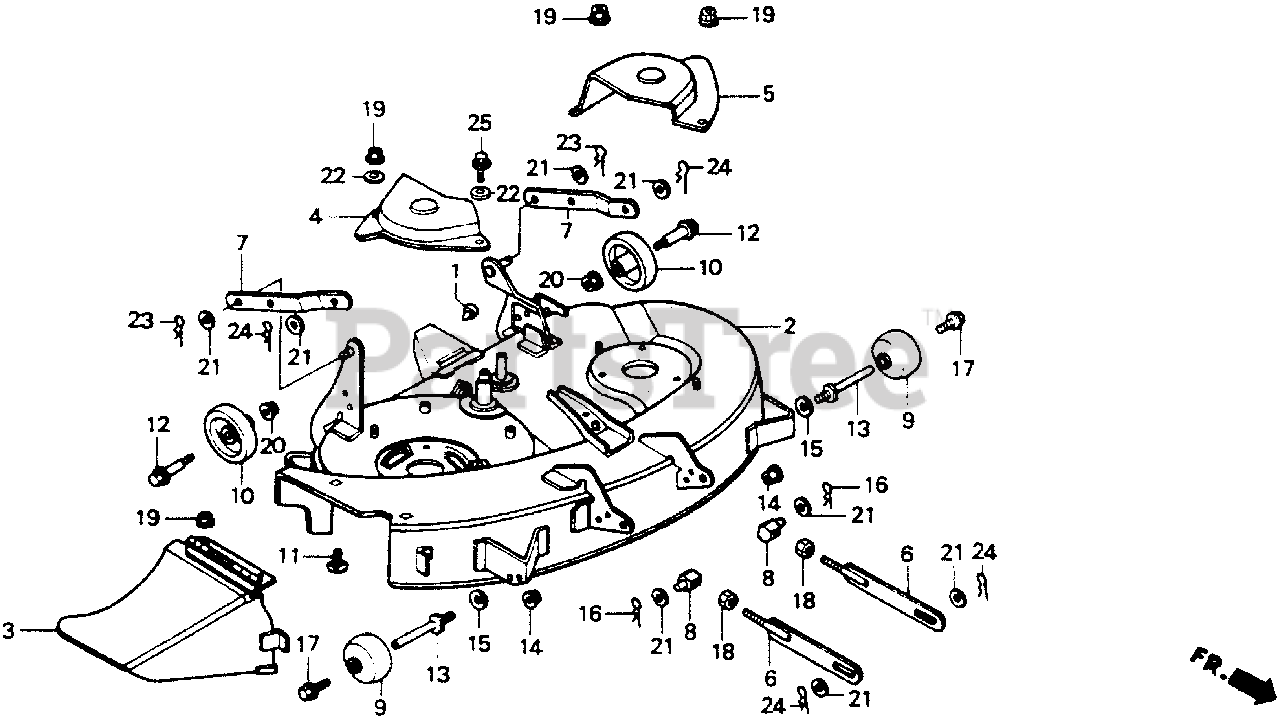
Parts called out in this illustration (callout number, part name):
1	RUBBER, STOPPER
2	HOUSING, CUTTER (NOT AVAILABLE)
3	ADAPTER, DISCHARGE *NH190M* (VINTAGE GRAY METALLIC)
4	COVER, R. BELT *NH190M* (VINTAGE GRAY METALLIC)
5	COVER, L. BELT *NH190M* (VINTAGE GRAY METALLIC) (NOT AVAILABLE)
6	LINK, FR. DECK
7	LINK, RR. DECK
8	PIN, FR. LINK ADJUSTING
9	ROLLER, ANTI-SCALP
10	ROLLER, RR. ANTI-SCALP
11	BOLT, SPECIAL (9X15)
12	BOLT, ANTI-SCALP ROLLER
13	SHAFT, ANTI-SCALP ROLLER
14	NUT, FLANGE (12MM)
15	WASHER, SPECIAL (12MM) (NOT AVAILABLE)
16	PIN, LOCK (2.3MM)
17	BOLT-WASHER (8X12)
17	BOLT-WASHER (8X16)
18	NUT, HEX. (12MM)
19	NUT, FLANGE (8MM)
20	NUT, FLANGE (10MM)
21	WASHER, PLAIN (14MM)
22	WASHER, PLAIN (8MM)
23	PIN, COTTER (4X25)
24	PIN, LOCK (14MM)
25	BOLT, FLANGE (8X14)
